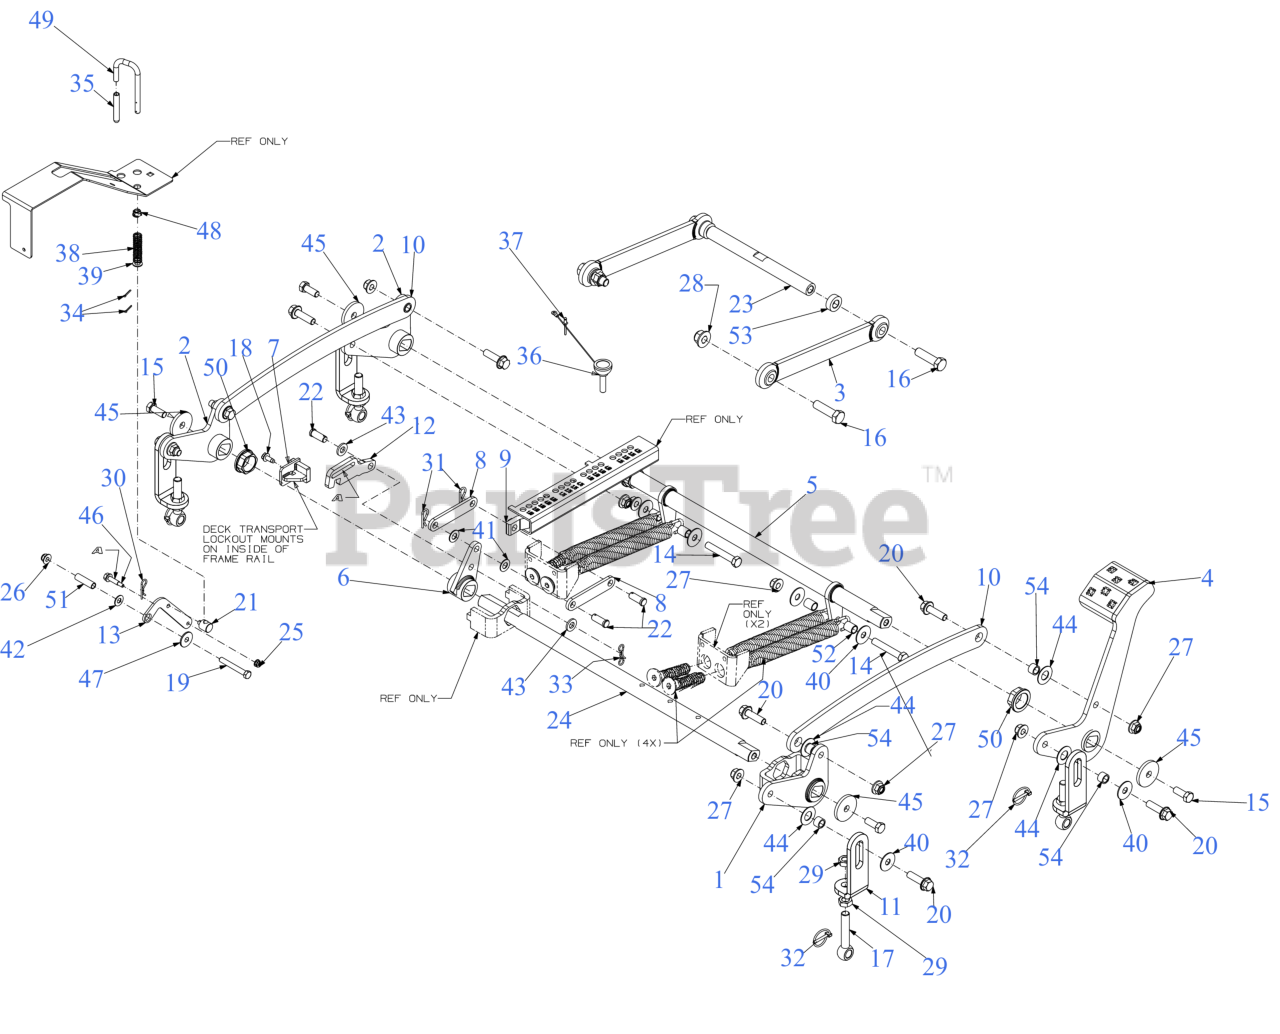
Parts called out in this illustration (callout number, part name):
5	FRONT DECK LIFT SHAFT
6	DECK LIFT HUB ASSEMBLY (LH)
7	LIFT LOCK MOUNT
8	DECK LIFT INDEX LINK
9	LIFT INDEX SLIDER ARM
12	LOCK LATCH BRACKET
13	PIVOT LOCKOUT LINK
14	SCREW-HEX 1/2-13 x 3.00
15	SCREW 1/2-13 x 1.25 GR5
16	SCREW 5/8-11 x 2.25 GR5
17	EYE BOLT 5/8-11 x 3.63
18	SCREW 5/16-18 x .750
19	SCREW 3/8-16 x 2.75 GR5
20	FLANGE BOLT 1/2-13:1.75:GR5
21	BRAKE ROD FERRULE
22	CLEVIS PIN .500 x 1.25
23	FRONT LIFT SHAFT
24	LIFT SHAFT 1.25 DIA
25	FLANGE LOCK NUT
28	FLANGE LOCK NUT
30	INTERNAL COTTER PIN
31	COTTER PIN
32	LYNCH PIN .1875
33	PIN:COTTER
34	COTTER PIN 3/32
36	DECK LIFT KNOB
37	FULL TUBULAR RIVET
38	COMPRESSION SPRING .656 ODX 2.445"
39	FLAT WASHER
40	WASHER .51 x 1.5 x .07
41	FLAT WASHER .510 x .995
42	FLAT WASHER
43	FLAT WASHER .510 x 1.000 x .125
44	FLAT WASHER
45	FLAT WASHER .53"x2.125"x.25"
46	SHOULDER SCREW
47	SHOULDER SPACER
48	BUSHING .380 ID
49	DECK LOCK OUT ROD
50	FLANGE BEARING
52	SPACER 0.535 x 0.68 x 0.83
53	SPACER .635X1.25X.445
